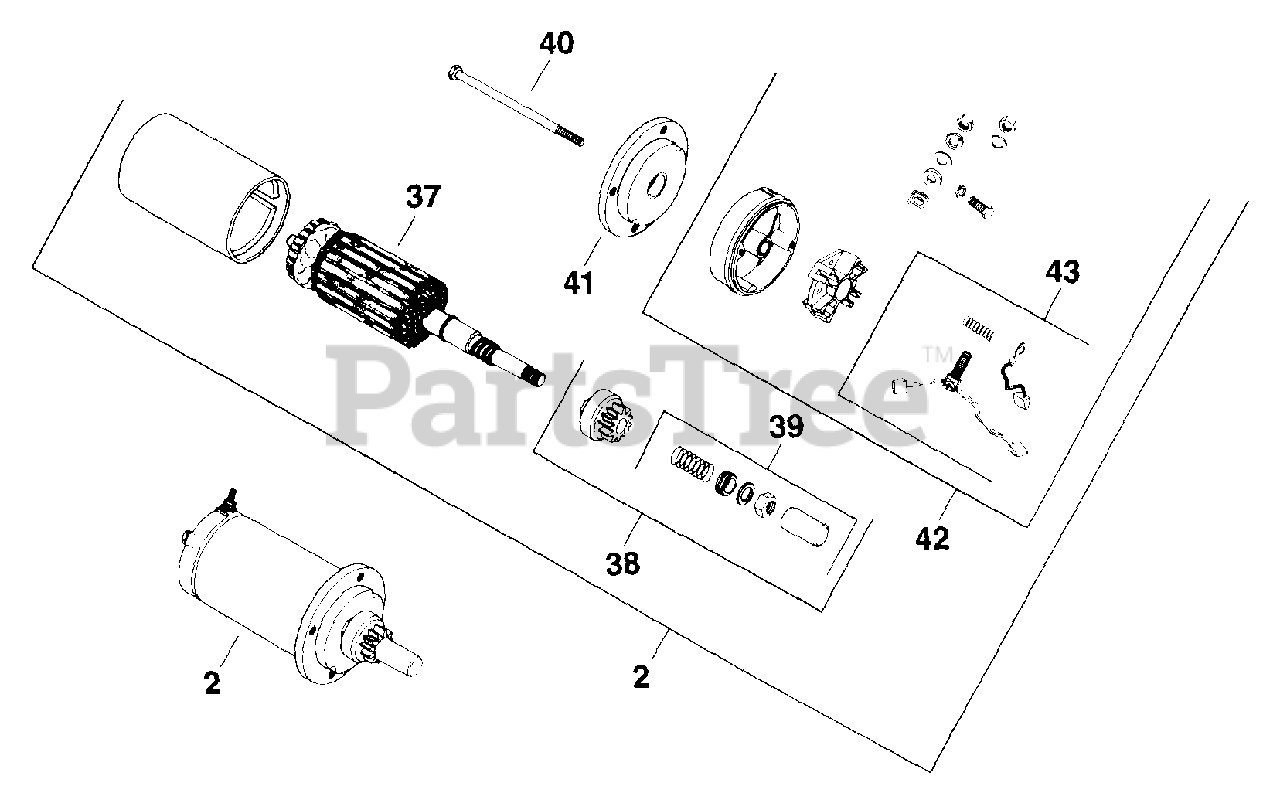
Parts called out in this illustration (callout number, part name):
2	STARTER - USE 48 098 04
37	ARMATURE - DISCONTINUED
38	DRIVE KIT - USE 48 755 40
39	DRIVE KIT - USE 48 755 40
40	BOLT - (#DSC)
41	CAP - DISCONTINUED
42	CAP - DISCONTINUED
43	KIT - USE 52 755 15
A-277214-S	KIT, STARTER - DISCONTINUED
